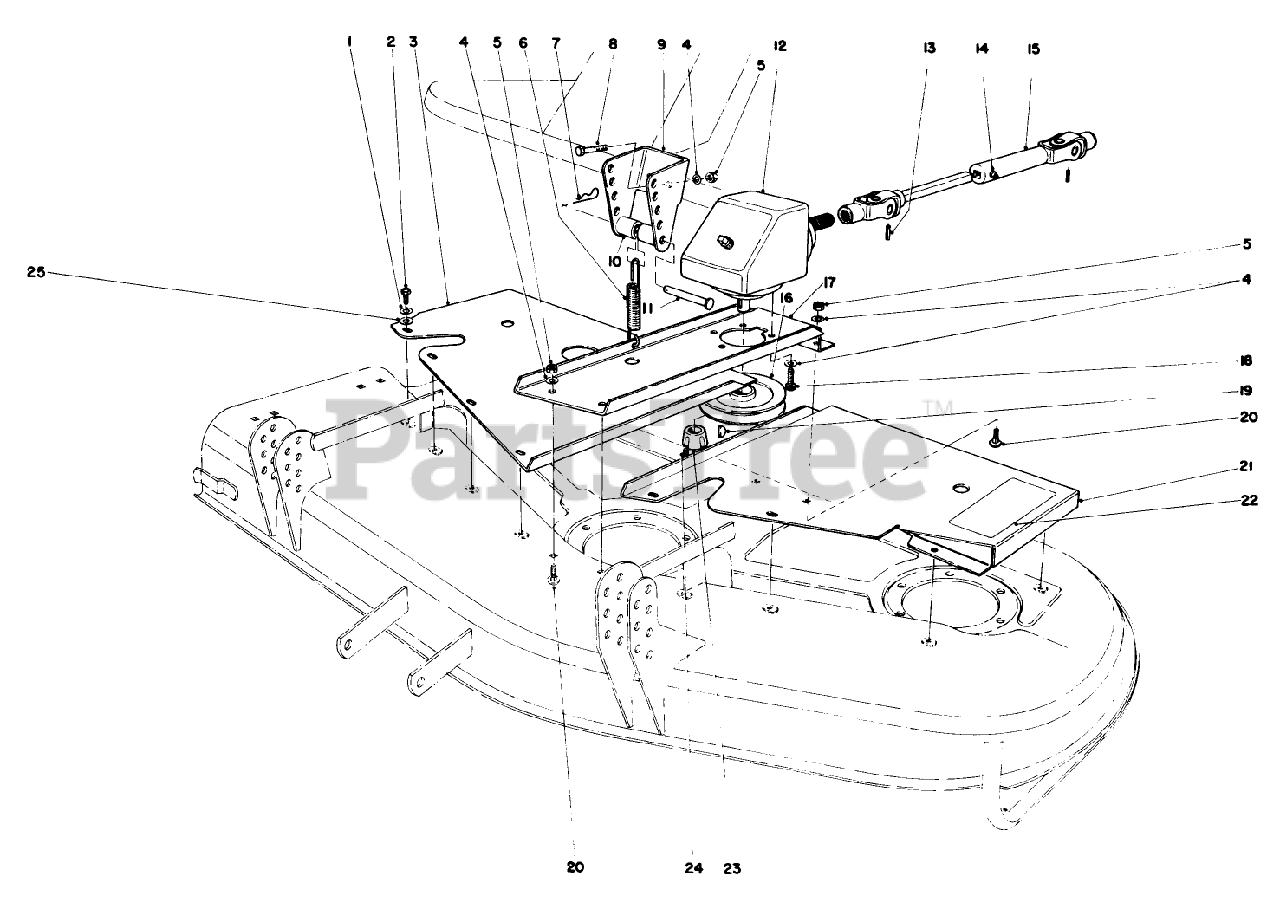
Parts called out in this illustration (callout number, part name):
1	WASHER-LOCK
2	SCREW THD 1/4 20 5/8
3	RH COVER WA R
4	WASHER-LOCK
5	NUT-HEX
6	Extension Spring
7	PIN-HAIR
8	SCREW-HH
9	Bracket-Spring
10	SPACER
11	PIN-CLEVIS
12	GEAR BOX ASM
13	PIN-ROLL
14	FITTING-GREASE
15	Pivot Nut
16	PULLEY WA BO
17	Base-Bear Box
18	SCREW-HSH
19	KEY-WOODRUFF
20	SCREW-CARR
21	LH COVER WA R
22	DECAL
23	BUSHING-LOCK, TAPER
24	SCREW-SET, HSH
25	WASHER-FLAT
